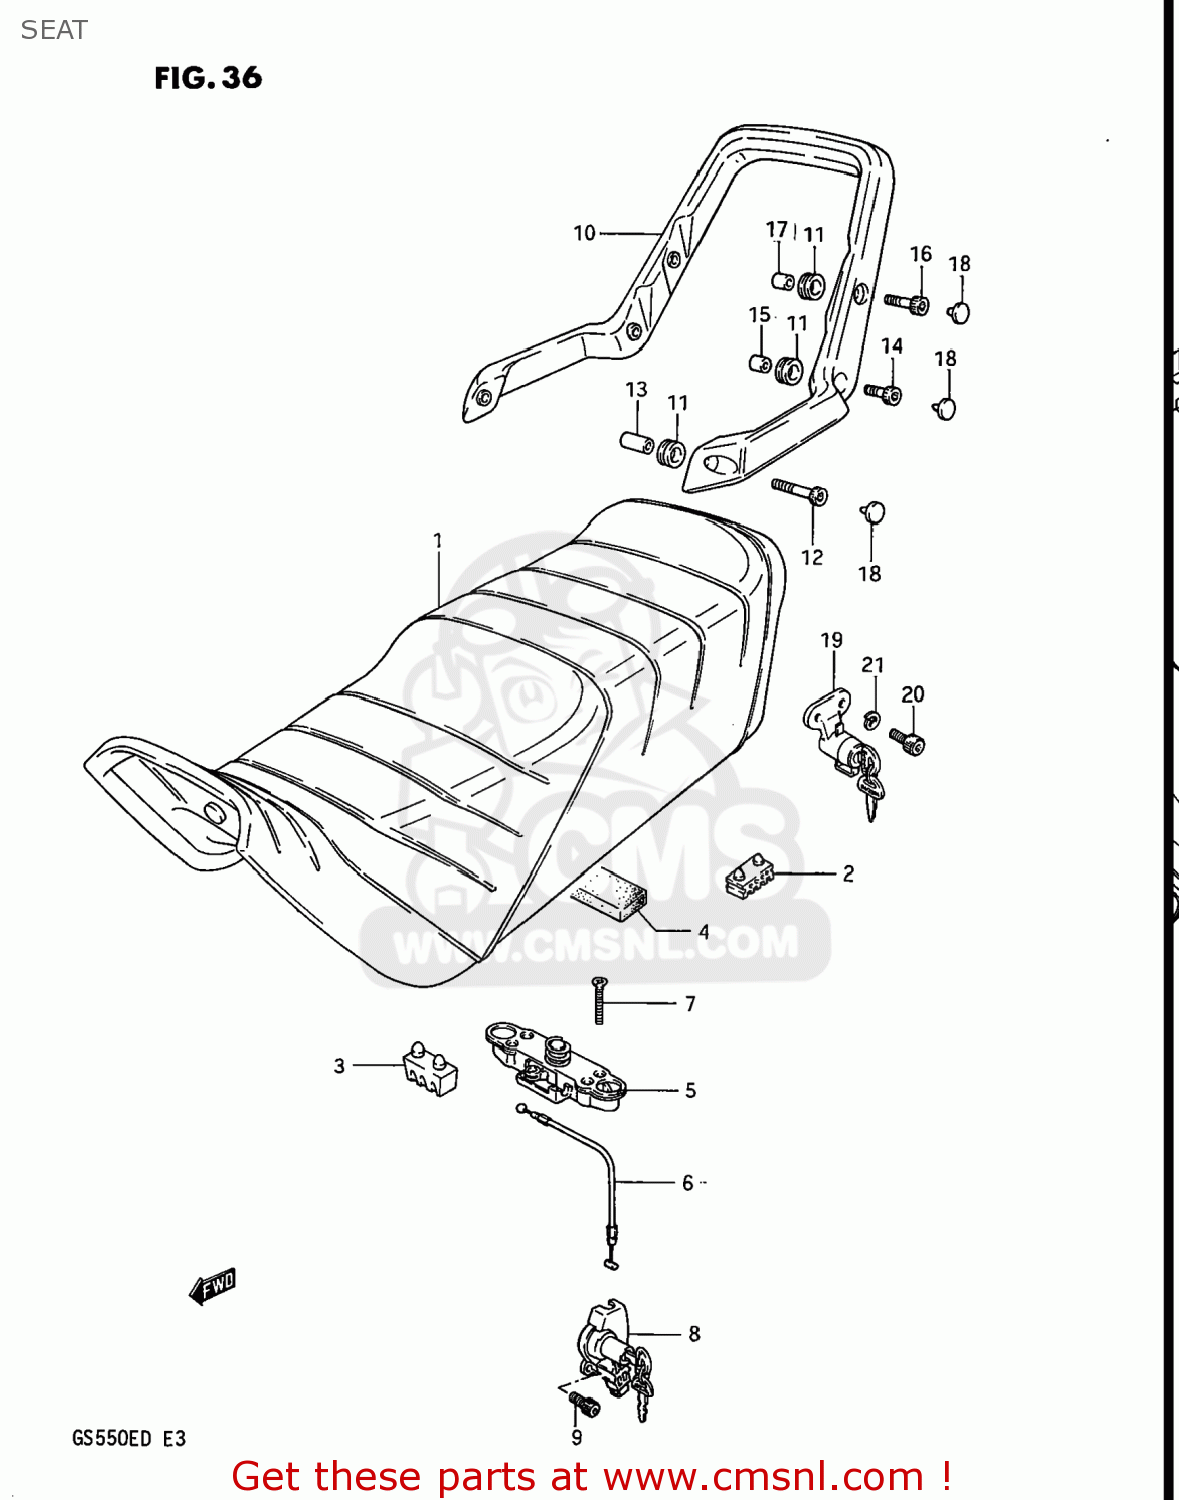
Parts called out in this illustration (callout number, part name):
1	SEAT ASSEMBLY
2	CUSHION,SEAT(40X20X15)
3	CUSHION,SUPPORT(50X25X32)
4	CUSHION(30X60X10)
5	LOCK ASSEMBLY,SEAT STRIKER
6	CABLE,SEAT LOCK
7	SCREW
8	LOCK ASSEMBLY,SEAT & HELMET
9	BOLT
10	HANDLE,PILLION RIDER
11	GROMMET,PILION RIDER HANDLE
12	BOLT
13	SPACER,PILLION RIDER HOLDER
14	BOLT
15	SPACER,PILLION RIDER HOLDER
16	BOLT
17	SPACER,PILLION RIDER HOLDER
18	CAP(OD:10)
19	LOCK ASSEMBLY,HELMET
20	BOLT
21	LOCK WASHER
